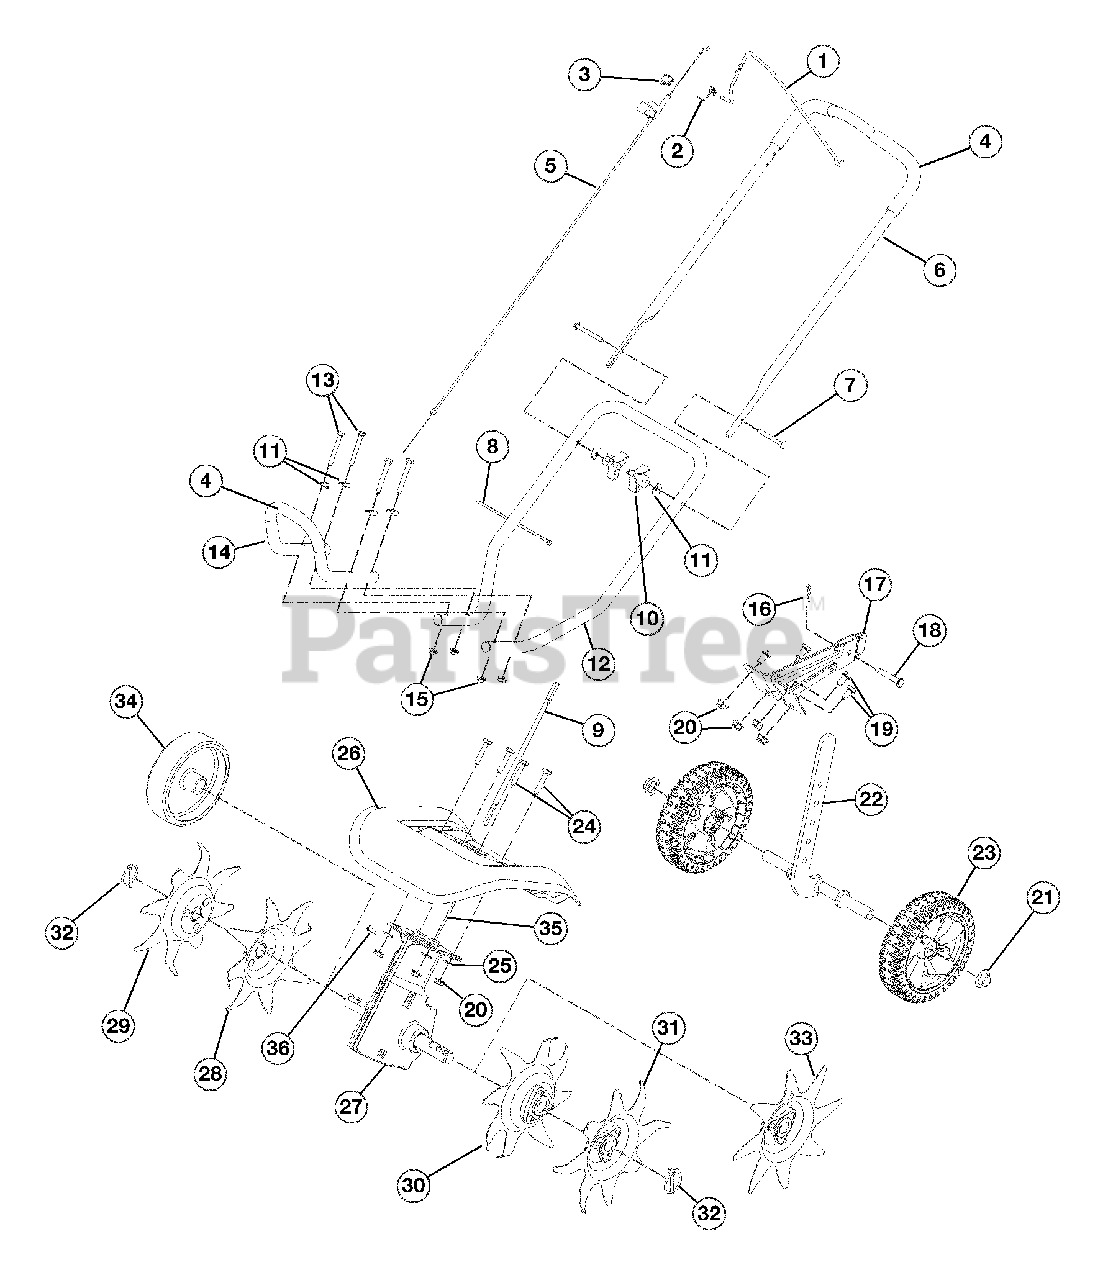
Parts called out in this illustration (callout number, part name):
1	Trottle Control
2	Torsion Spring
3	On/Off Switch
4	Foam Grip
5	Throttle Cable
6	Upper Handle
8	Cable Tie
9	Flex Shaft
11	Shoulder Washer
12	Lower Handle
13	Screw
14	Front Handle
15	Lock Nut
16	Cotter Pin
17	Tailpiece Bracket Assembly
18	Clevis Pin
19	Cap Screw
20	Lock Nut
21	Cap Push
22	Wheel Support Bracket Assembly
23	Wheel
24	Cap Screw
25	Washer
26	Tine Shield
27	Gear Box Assembly
28	Inner Tine (right side)
29	Outer Tine (right side)
30	Inner Tine (left side)
31	Outer Tine (left side)
33	Edger Tine
34	Edger Wheel
35	Drive Shaft Housing
36	Anti Rotation Screw
